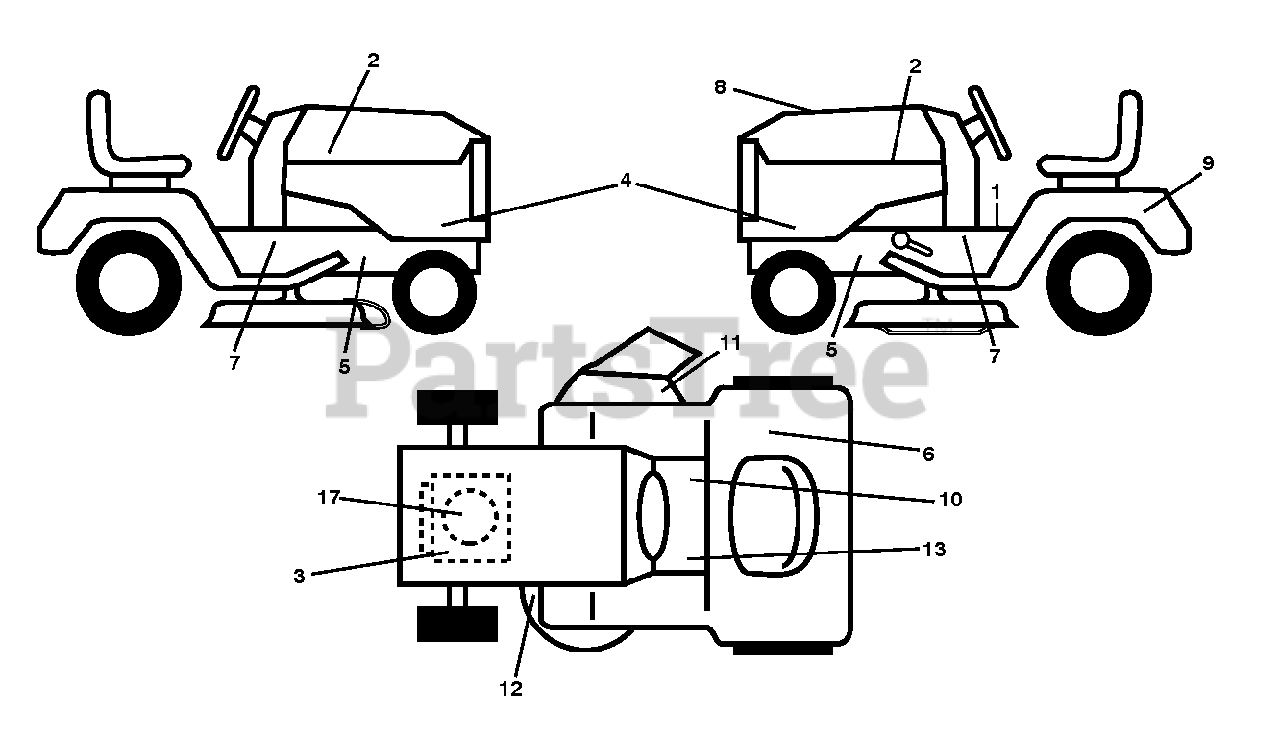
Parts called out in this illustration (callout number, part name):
1	LABEL
2	RP.DECAL.BADGE.170MM.TEXTLOGO
3	DECAL
6	Decal, Fender 100 DB/CE
8	DECAL DECAL.RPL.BSM21.PB.SRD.3
9	DECAL BTRY SYMBOLS
10	DECAL PARK BRAKE
11	Decal, Warning Deflector Cut Finger
12	Decal, Mower V-Belt Schematic
13	DECAL
17	DECAL
